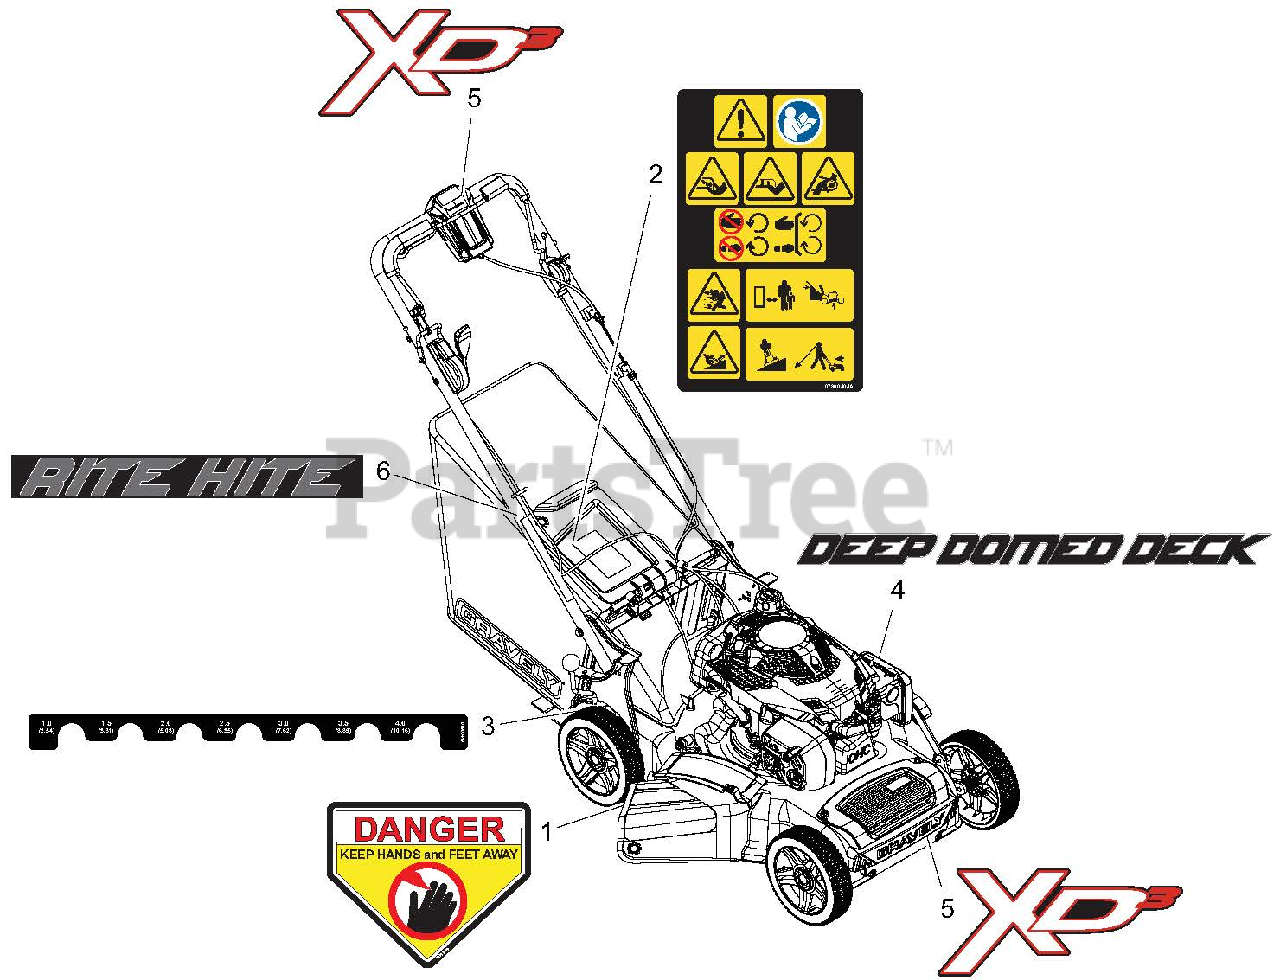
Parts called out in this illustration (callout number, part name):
1	DECAL, DANGER
2	DECAL, MAIN SAFETY WAW LM
3	DECAL, HOC
4	DECAL, DEEP DOME DECK
5	DECAL, GRAVELY XD3 STYLE
6	DECAL, RITE HITE
